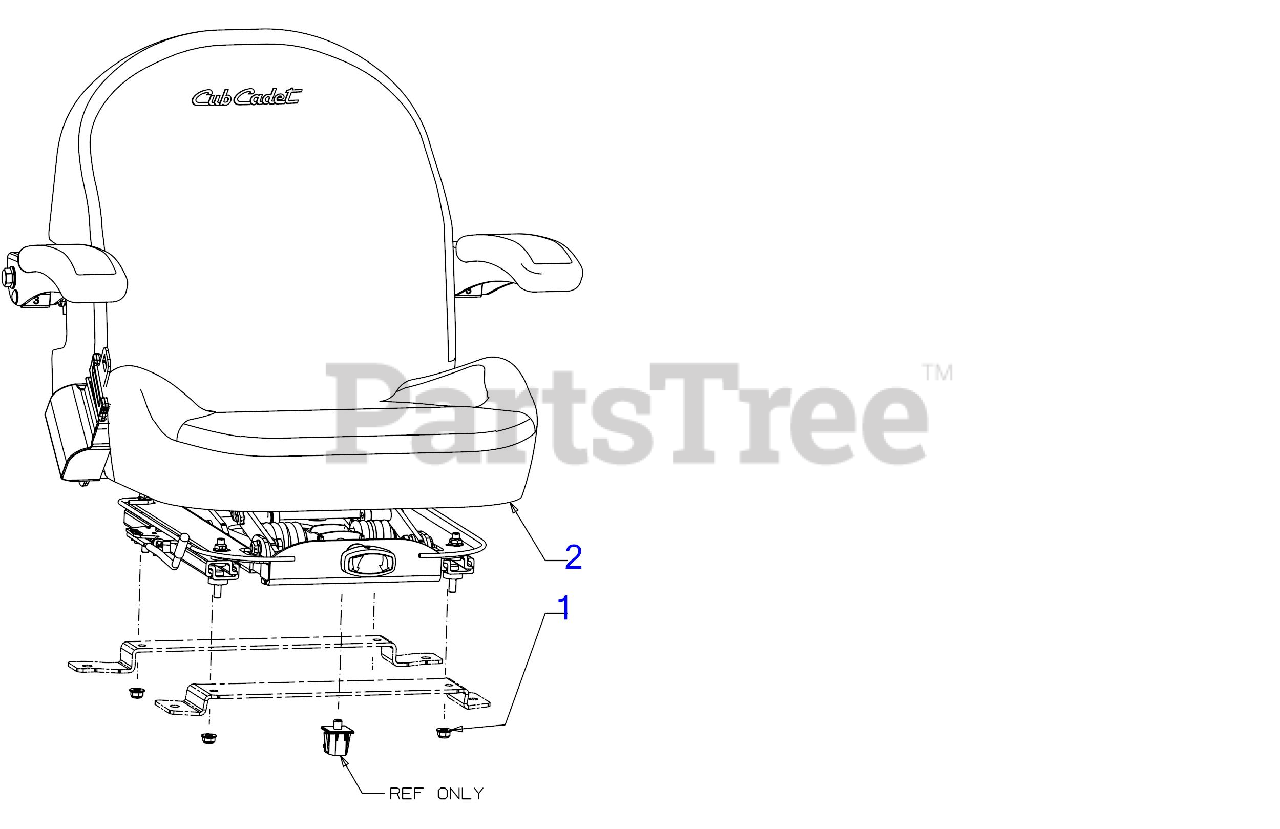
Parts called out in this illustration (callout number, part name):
1	FLANGE LOCK NUT 5/16-18
2	SEAT ASSEMBLY (ADD SI PARTS)
2	SEAT BACK COVER FOR 757-05084
2	CUSHION COVER FOR 757-05084
